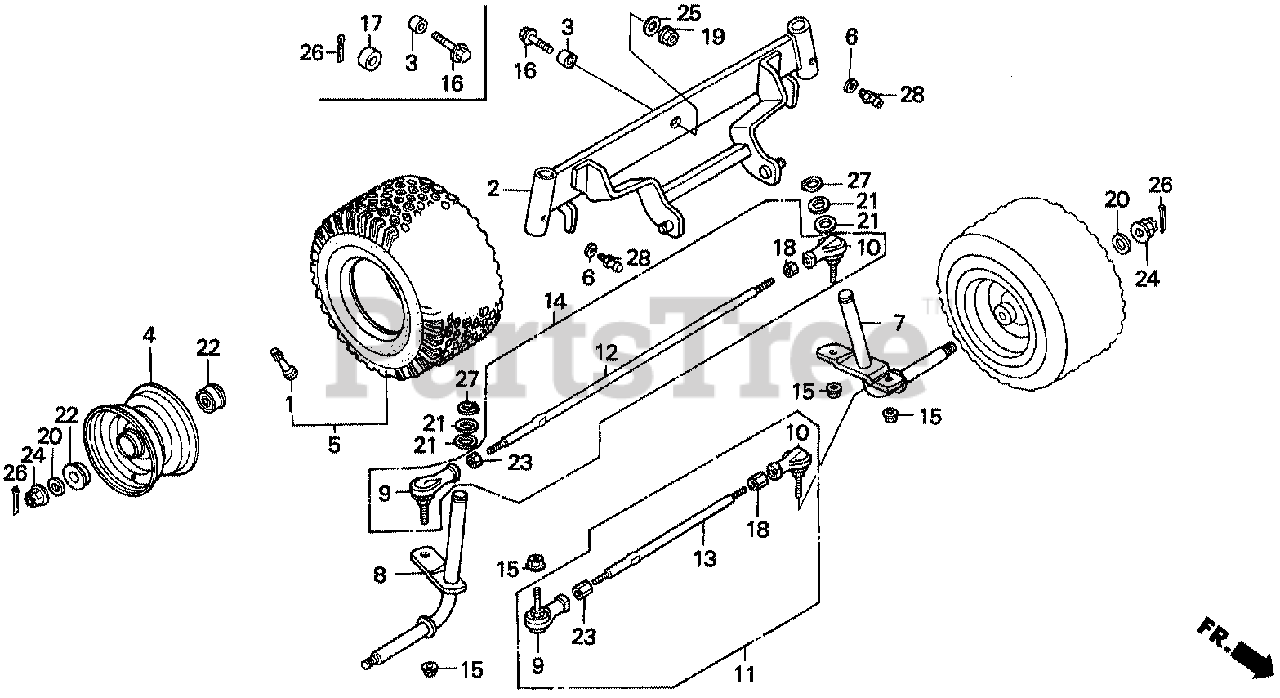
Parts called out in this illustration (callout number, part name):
1	VALVE, RIM
3	COLLAR, FR. AXLE
4	WHEEL, FR. *NH35M* (CLOUD SILVER METALLIC)
5	TIRE, TURF (11X4.00-5)
6	COLLAR (6.5X11X3)
7	KNUCKLE, L.
8	KNUCKLE, R.
9	JOINT, BALL (ER1O)
10	JOINT, BALL (ERL1O)
11	TIE ROD ASSY. B
12	TIE ROD (A)
13	TIE ROD (B)
14	TIE ROD ASSY. A
15	NUT, SELF-LOCK (10MM)
16	BOLT, FLANGE (10X55)
17	COLLAR, MUFFLER SETTING
18	NUT, HEX. (10MM)
19	NUT, AXLE (10MM)
20	WASHER, SPECIAL (12MM)
21	WASHER, THRUST (17MM)
22	BEARING, RADIAL BALL
23	NUT, HEX. (10MM)
24	NUT, CASTLE (12MM)
25	WASHER, PLAIN (10MM)
26	PIN, SPLIT (3.0X25)
26	PIN, SPLIT (3.0X45)
27	CIRCLIP (OUTER) (17MM)
28	NIPPLE, GREASE (A.T6) (M6X1.0)
